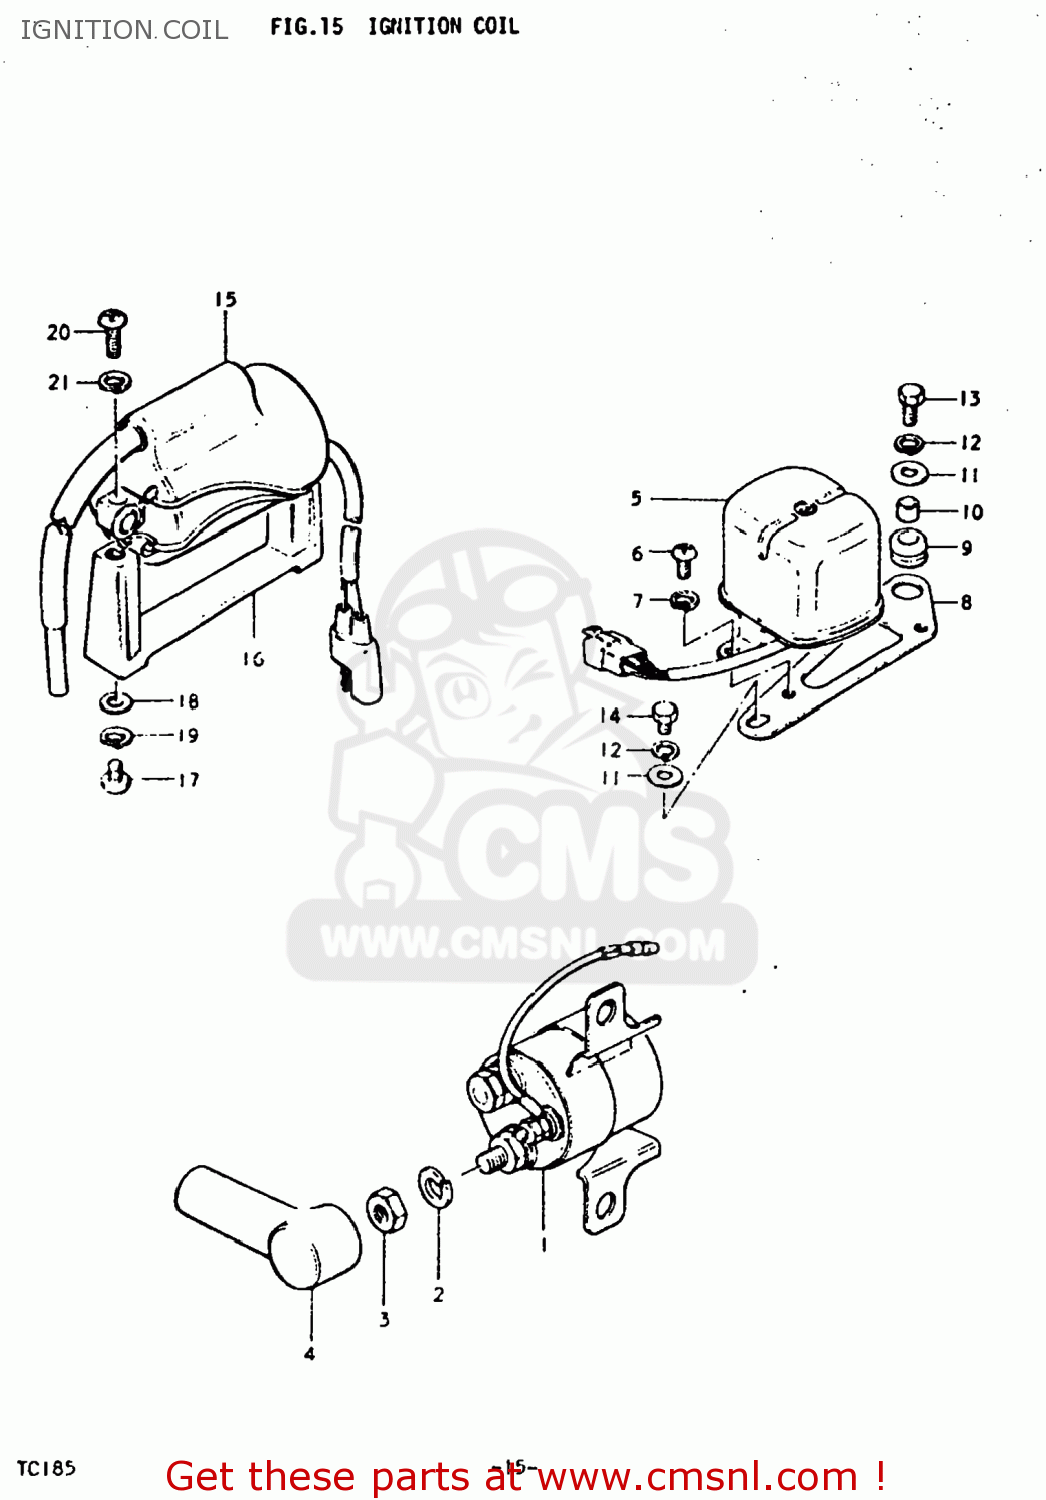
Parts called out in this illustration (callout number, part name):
1	RELAY ASSY,STARTING MOTOR
2	LOCK WASHER
3	NUT
4	CAP,STARTER RELAY
5	REGULATOR ASSEMBLY
6	SCREW
7	LOCK WASHER
9	CUSHION
10	SPACER (7X9X7)
11	WASHER (6.5X20X1.2)
12	LOCK WASHER
13	BOLT
14	BOLT
15	COIL ASSEMBLY,IGNITION
16	HOLDER,IGNITION COIL
17	Screw
18	WASHER
19	LOCK WASHER
20	SCREW
21	LOCK WASHER
